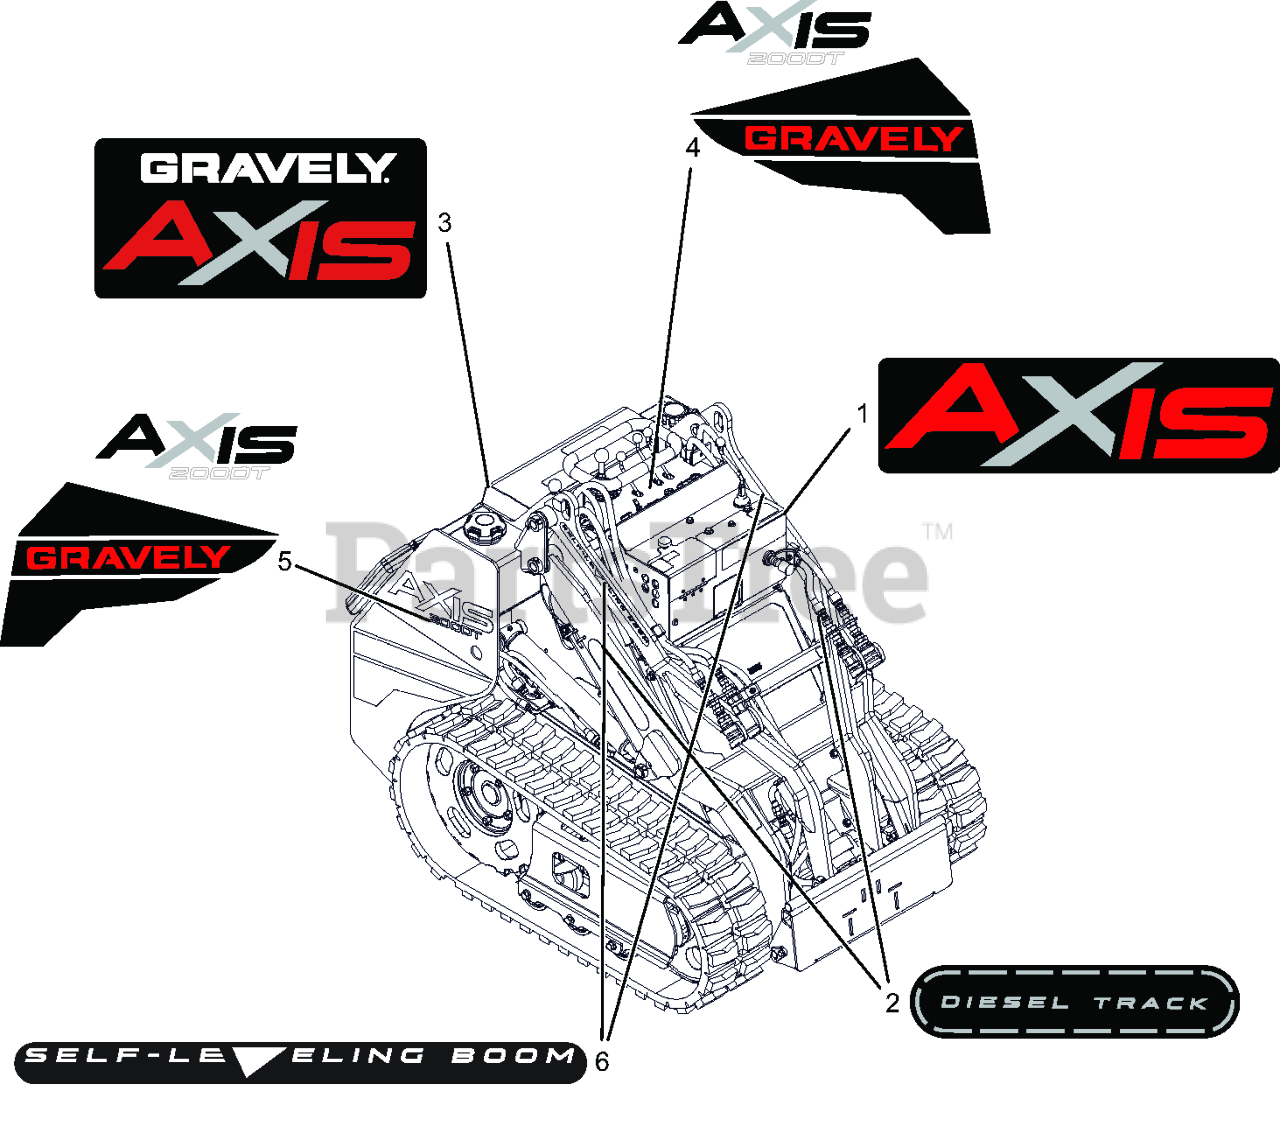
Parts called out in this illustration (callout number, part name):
1	DECAL, AXIS FRONT
2	DECAL, DIESEL TRACK
3	DECAL, AXIS REAR
4	DECAL, 200 DT LEFT
5	DECAL, 200 DT RIGHT
6	DECAL, SELF LEVELING
